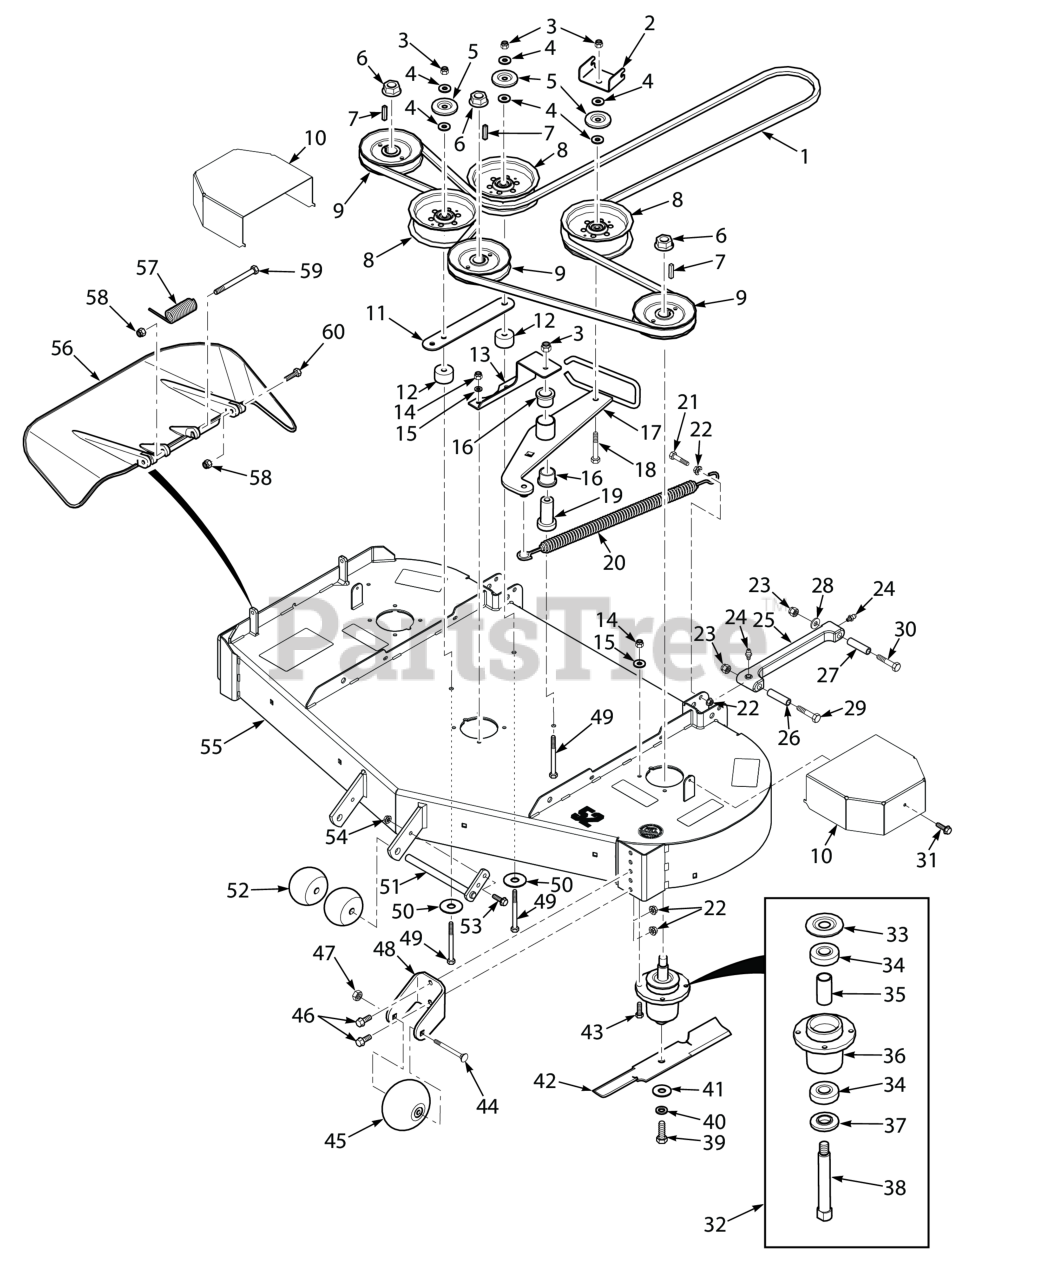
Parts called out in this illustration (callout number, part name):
1	Belt, Cutter Deck - 52
2	Bracket, Belt Guide
3	HEX NUT, ELASTIC STOP LOCK, 3/8-16
4	Flatwasher, 3/8 (.391 x .938 x .105 HD) Grade 8
5	Quick Pin, 5/16" Dia.
6	Nut, 3/4-16 Spriral Lock
7	Key, 1/4 x 1/4 x 1.25" Pulley Mtg.
8	Pulley, 5" Idler
9	Pulley, 5.73" OD - 25mm Bore
10	Belt Cover, SZL
11	Brace, Pulley
12	Spacer, Idler Pulley
13	Support, Idler Pivot - 52
14	Lock Nut, 5/16-18 Elastic Stop Grade 8
15	Lockwasher, 5/16 (.317 x .586 x .078) Helical Spring
16	Bearing, Plastic
17	Idler Arm (incl. item #15)
18	Capscrew, Hex Head 3/8-16 x 2-1/2"
19	Pivot, Idler
20	Spring, Cutter Deck Idler
21	Bolt, Hex Head 3/8-16 x 1-1/2" Grade 8 Black
22	NUT, 3/8-16 SERRATED FLANGE HEX HEAD
23	HEX LOCKNUT, ELASTIC STOP, 1/2-13
24	GREASE FITTING, STR. 1/4-28 SELF TAP.
25	Pusharm Assembly, LH
26	Spacer, Pusharm - Deck
27	Spacer, Pusharm - Axle
28	Flatwasher, 1/2 - .531 x 1.062 x .095
29	Bolt, Hex Head 1/2-13 x 3-1/2"
30	Bolt, Hex Hd. 1/2-13 x 2-1/2" (lower)
31	Screw, 1/4-20 x .375"
32	Spindle Assembly
33	Debris Shield
34	Bearing
35	Spacer, Bearing
36	Spindle Housing Assembly
37	Protector, Bearing
38	Shaft, Spindle
39	Bolt, Hex Head 5/8-11 x 1-1/2"
40	Lockwasher, 5/8" Spring
41	Flatwasher, 5/8-.688 x 1-3/4 x .134 HD
42	Cutter Blade, 18" (52V)
43	Bolt, Hex Head 5/16-18 x 1-1/2" Grade 8
44	Bolt, Hex Head 3/8-16 x 3-1/2"
45	Bolt, Carriage 3/8-16 x 4"
46	Capscrew, 3/8-16 x 1.0" Serrated Flange Hex Hd
47	Bolt, Hex Head 3/8-16 x 1" Ser. Flg.
48	Bracket, Anti-Scalp, (Black)
49	Bolt, Hex Head, 3/8-16 x 3-1/2"
50	Flatwasher, 3/8-.406 x 2.25" x .1875
51	Shaft Weldment, Guide Roller
52	Wheel, Anti-Scalp
53	Bolt, Heax Head 5/16-18 x 1" (48V / 52V)
54	Nut, Flange Head Elastic Stop 5/16-18
55	Cutter Deck w/Decals, SWZT52H
56	Discharge Chute Assy. SFZ52
57	Spring, Discharge Chute
58	HEX NUT, ELASTIC STOP LOCK, 5/16-18
59	Bolt, 5/16-18 x 4-3/4" Hex Head
60	Bolt, Hex Head 5/16-18 x 1-1/2" - Front
